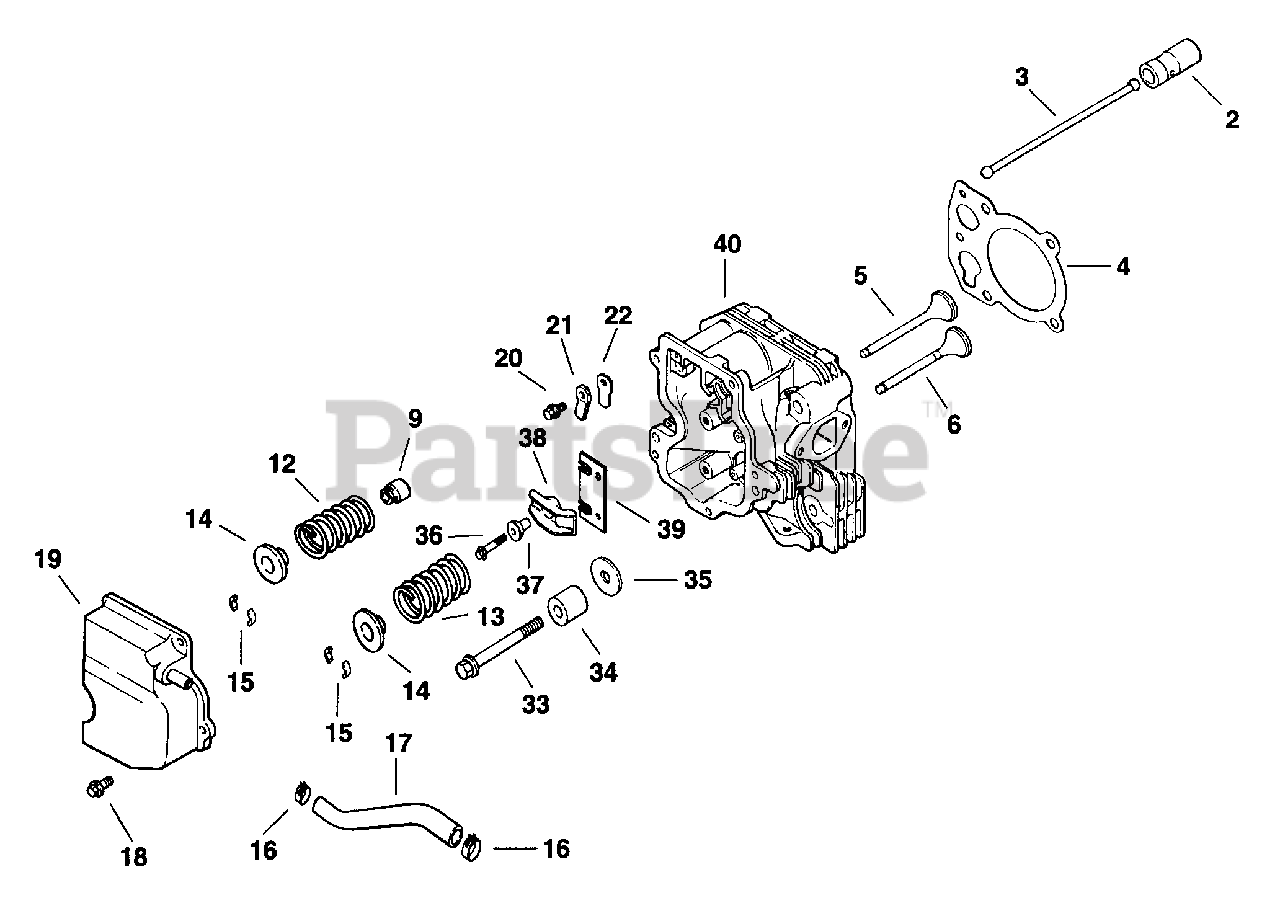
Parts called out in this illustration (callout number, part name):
2	LIFTER - USE 12 351 02
4	GASKET, CYLINDER HEAD
5	VALVE, INTAKE
5	VALVE, INTAKE (.25 MM)
6	VALVE, EXHAUST
6	VALVE, EXHAUST (.25 MM)
13	SPRING
14	RETAINER, VALVE SPRING - USE 25 173 28-S
15	KIT, RETAINER
16	CLAMP, HOSE 1/2" USE 25 237 14-S
18	SCREW - USE M-645020
20	SCREW - USE M-545010
21	RETAINER - UE 66 018 04-S
22	REED, BREATHER
34	SPACER, HEAD BOLT EXHAUST PORT
35	WASHER, FLAT 13/32"
36	Screw, hex. flange M6x1.0x34
37	ROCKER ARM PIVOT - USE KIT 12 755 74
38	ROCKER ARM - SEE PARTS BULLETINS 182 FOR TWINS AND 200 FOR SINGLES
39	GUIDE PLATE - USE KIT 12 755 74
40	HEAD - USE 12 318 19-S
